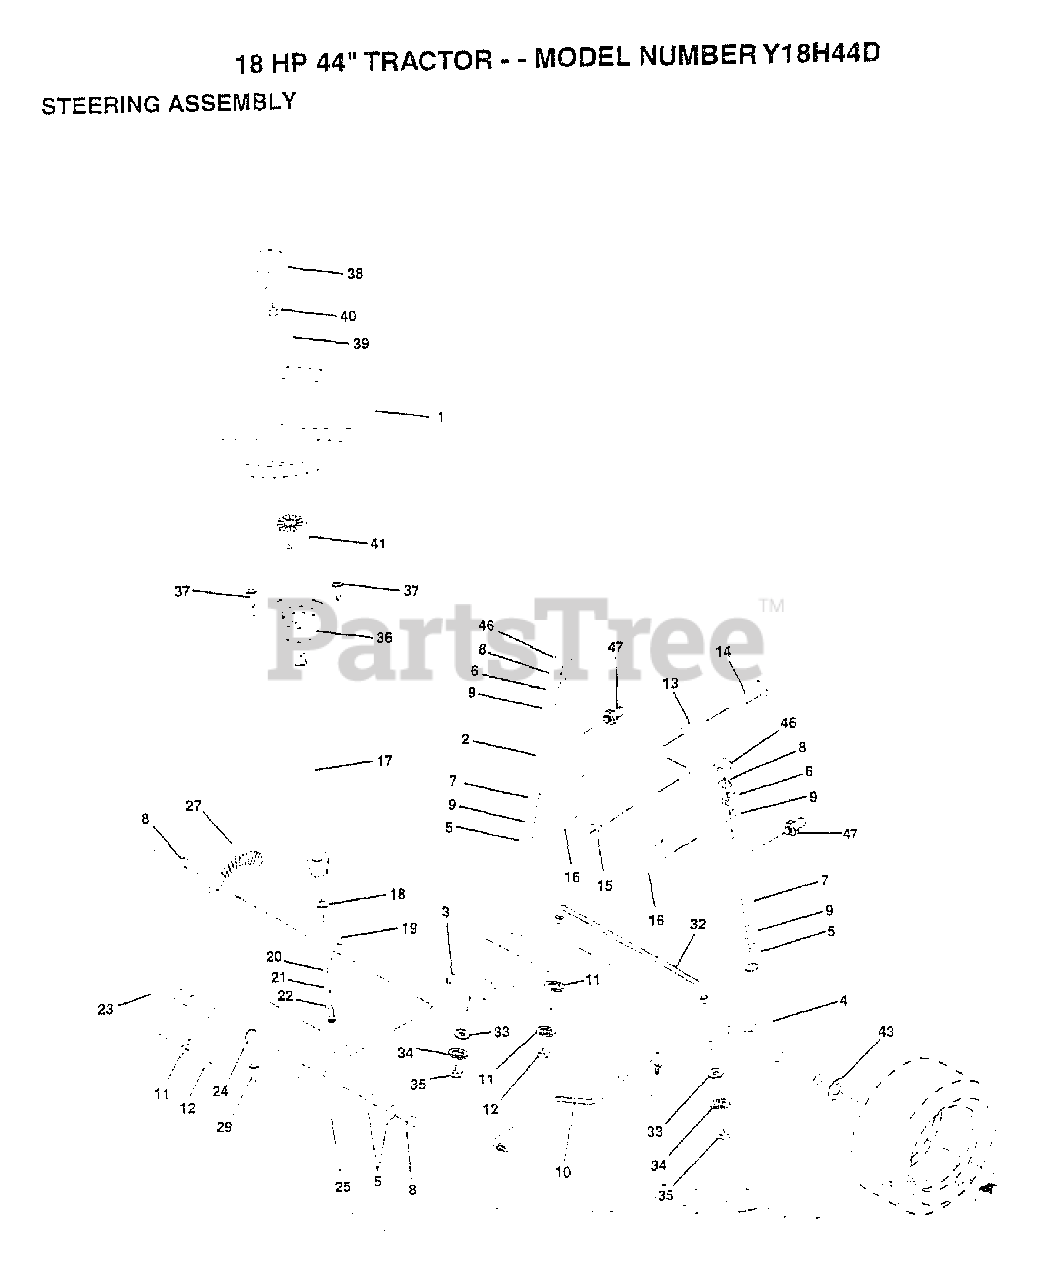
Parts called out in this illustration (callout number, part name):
2	AXLE ASM FRONT
3	SPINDLE LH
4	SPINDLE RH
5	WASHER .T
6	WASHER
7	WASHER
8	RING
9	COL. SRTG. BEAR.
11	LOCKWASHER
13	BEARING
14	BOLT HEX 5/8-11
15	"NUT-LOC,FLANGE LT"
16	AXLE PIN
18	THRUST WASHER
19	SUPPORT.SHAFT
21	LOCKWASHER
22	"SCREW,SPECIAL"
24	NYLINER T
25	"BRKT,STEERING"
27	GEAR SECTOR
29	SCREW
32	TIE ROD
33	WASHER M
34	LOCKWASHER
35	NUT.LOCK.5/16-24
38	INSERT STEERING
39	WASHER
41	ADAPTER LT
43	WASHER
46	CAP
47	ZERK M
